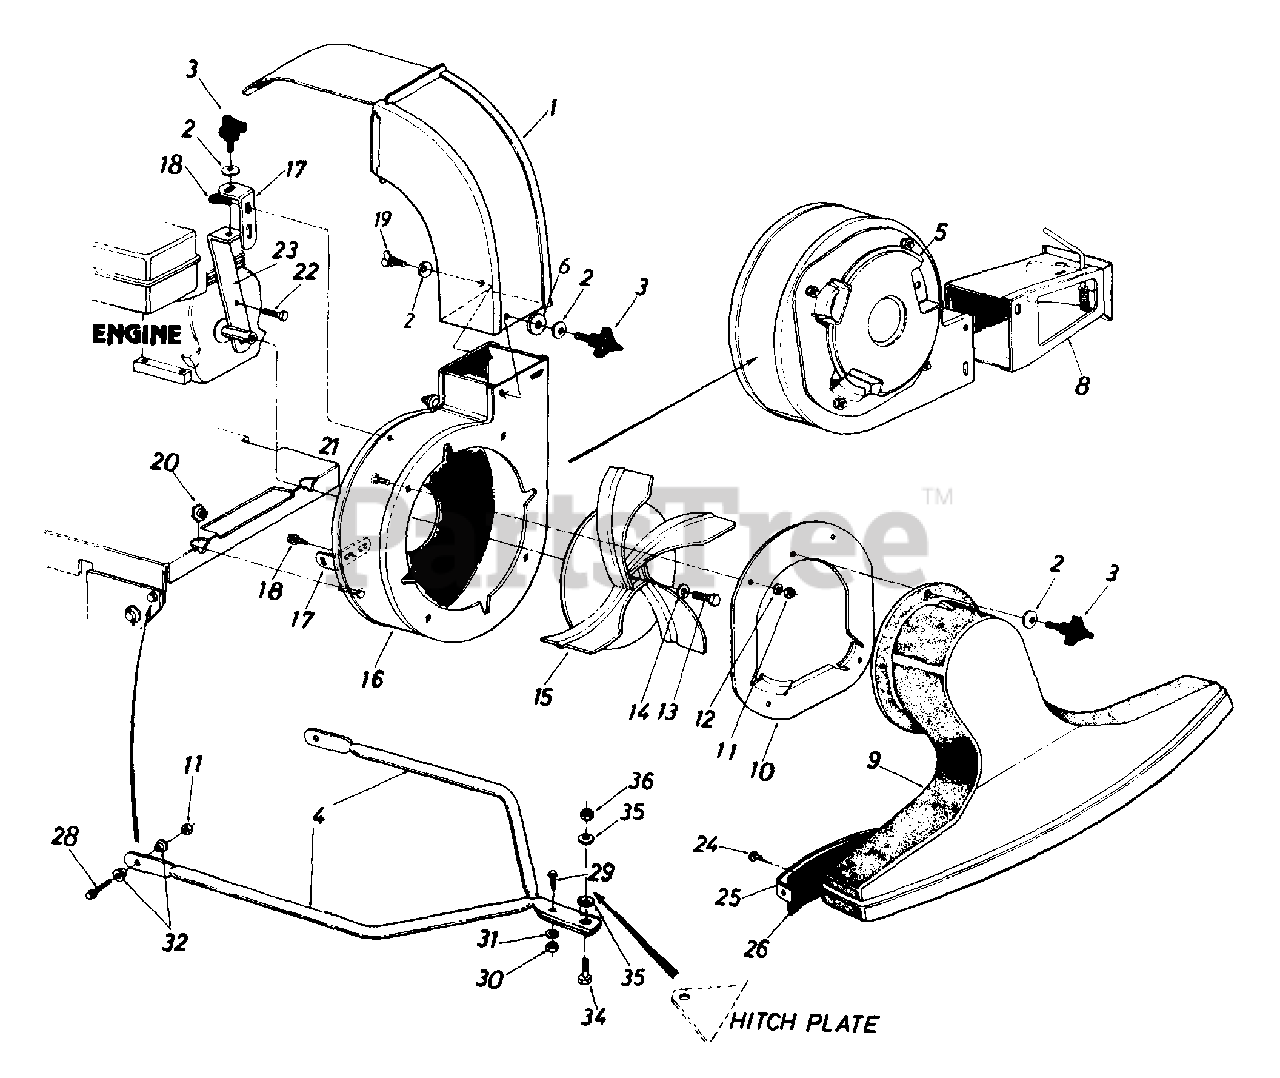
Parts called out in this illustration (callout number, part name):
3	Hand Knob
6	Fl-Wash..344" I.D. x 1.125" O.D.
10	Nozzle Plate Ass'y.
11	Hex Nut 5/16-18 Thd.
12	L-Wash. 5/16" I.D.
13	Hex Bolt 3/8-24 x 1.25" Lg.
14	L-Wash. 3/8" I.D. H.D.
15	Air Vane Plate Ass'y.
19	Thumb Screw 5/16-18
20	Hex Shoulder Nut.50 I.D.
21	Carriage Bolt 5/16-18 x .62"
22	Hex Locking 8olt 5/16-24 x .75" Lg.
28	Hex Bolt 5/16-18 x 1.00" Lg.
29	Truss Mach. Scr. 1/4-20 x .75"
30	Hex Nut 1/4-20 Thd.
31	l -Wash. 1/4" I.D.
32	Shoulder Spacer
34	Shld. Bolt .496 Dia.
35	Belleville Wash..39" I.D. x 1.12" O.D.
36	Hex Jam L-Nut 3/8-26 Thd.
